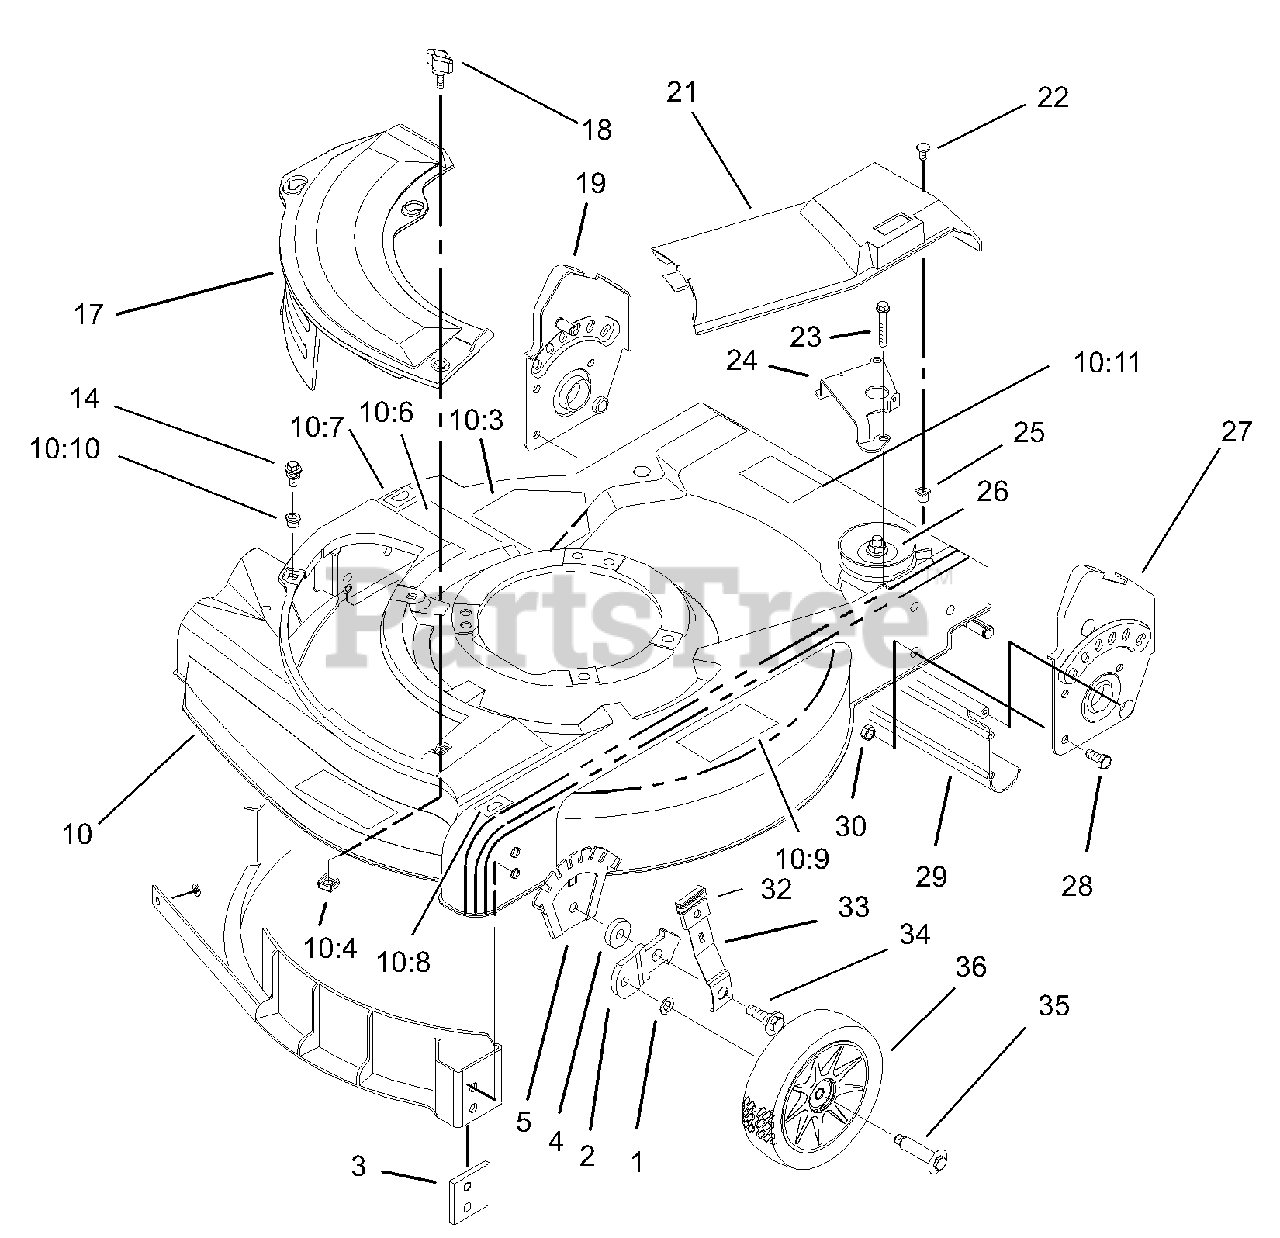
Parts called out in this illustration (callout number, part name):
2	BRACKET-HEIGHT ADJUSTMENT, WHEEL
3	PLATE-BAFFLE
4	WASHER-WHEEL
5	PLATE-HEIGHT, ADJUSTMENT
10	Housing-Service (only on: 10324c)
10	Deck ASM (only on: 10323, 10324)
10:3	Decal-Danger (only on: 10324c)
10:3	Decal-Danger (only on: 10323, 10324)
10:4	NUT-CAGE
10:6	Decal-Warning (only on: 10323, 10324)
10:6	Decal-Warning (only on: 10324c)
10:7	Decal-HOC, LH (only on: 10323, 10324)
10:7	Decal-HOC,LH (only on: 10324c)
10:8	Decal-HOC,RH (only on: 10324c)
10:8	Decal-HOC, RH (only on: 10323, 10324)
10:9	Decal-Warning (only on: 10323, 10324)
10:9	Decal-Warning (only on: 10324c)
10:10	NUT-CLIP
10:11	Decal-Manual (only on: 10324c)
14	Screw-Sems (only on: 10323)
17	PLATE-MULCH
19	RH BRACKET ASM
21	COVER-DRIVE
22	SCREW-THREAD CUT
23	SCREW-HWHTF
24	Guide-Transmission
25	NUT-CLIP
26	GEAR CASE ASM
27	LH BRACKET ASM
28	SCREW-HH
29	SHIELD-TRAILING
30	NUT-LOCK, NI
32	KNOB-LEVER, HEIGHT ADJUSTMENT
33	ARM-FRONT SPRING
34	BOLT-SHOULDER
35	BOLT-SHOULDER
36	WHEEL AND TIRE ASM
